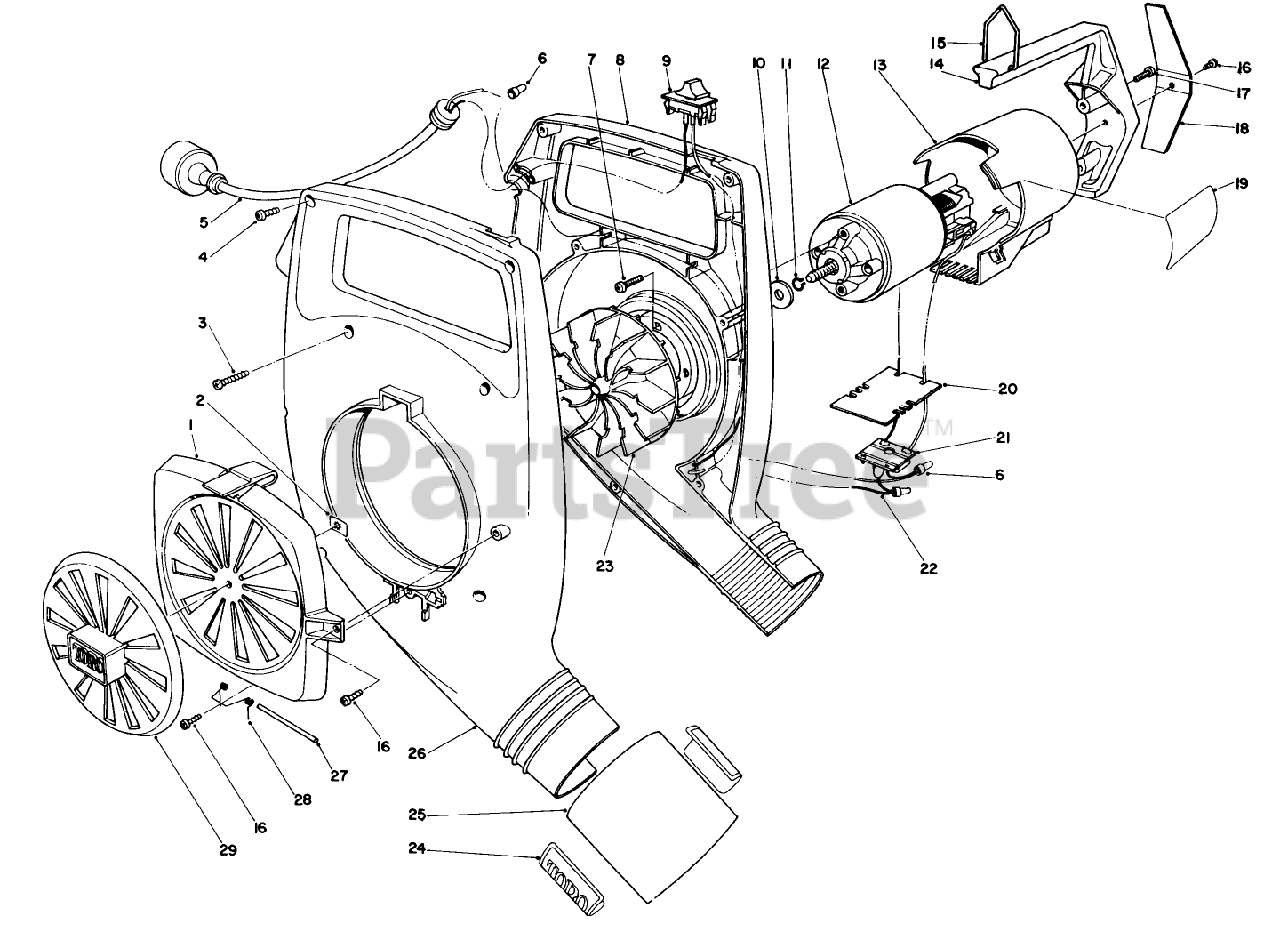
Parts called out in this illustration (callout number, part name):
2	PUSH NUT
3	SCREW
4	Screw
5	Power Cord Assembly
6	CONNECTOR
7	SCREW
8	LH HOUSING
9	Switch (Model 51530)
10	Washer
11	Retaining Ring
12	Motor
13	Motor Cover
14	Handle
15	HANGER
16	SCREW
17	SCREW
18	WARNING PLATE
19	DECAL - 400TX
20	Mounting Board
21	P.C. Board Assembly
22	LEADWIRE ASM
23	Impeller Assembly
24	Decal-Tube Collar
25	Sleeve-Ferrule
26	Housing-Inlet Side
27	HINGE PIN
28	Spring
29	Inlet Cover Housing (Incl. Ref. #29)
